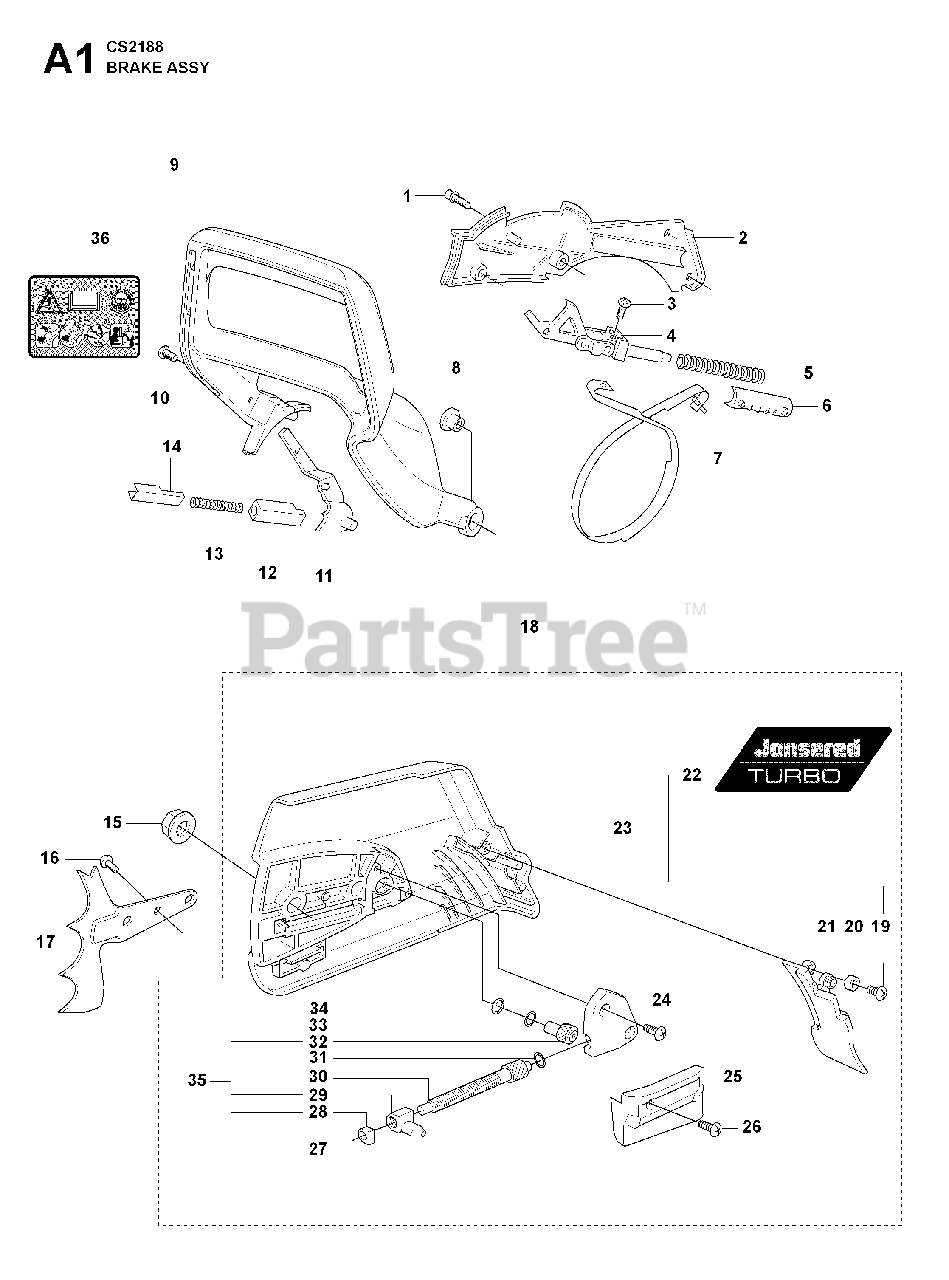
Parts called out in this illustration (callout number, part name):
4	KNEE LINK
5	BRAKE SPRING
6	%SUPPORT
7	BRAKE BAND
9	CHAIN BRAKE ASSY
11	BRAKE LEVER
13	LOCK SPRING
14	PROTECTOR
15	NUT M8 FLANGE
17	FELLING DOG
18	CLUTCH COVER
19	SCREW
20	WASHER
21	PROTECTOR
22	DECAL
23	CLUTCH COVER
24	SCREW
25	GUIDE
26	SCREW
27	COVER
28	SLEEVE
29	COUPLING
30	WORM SCREW / ADJUSTER
31	WASHER
32	RP ADJUSTER
33	WASHER
34	O-RING
35	KIT-CHAIN TENSIONER
36	DECAL
